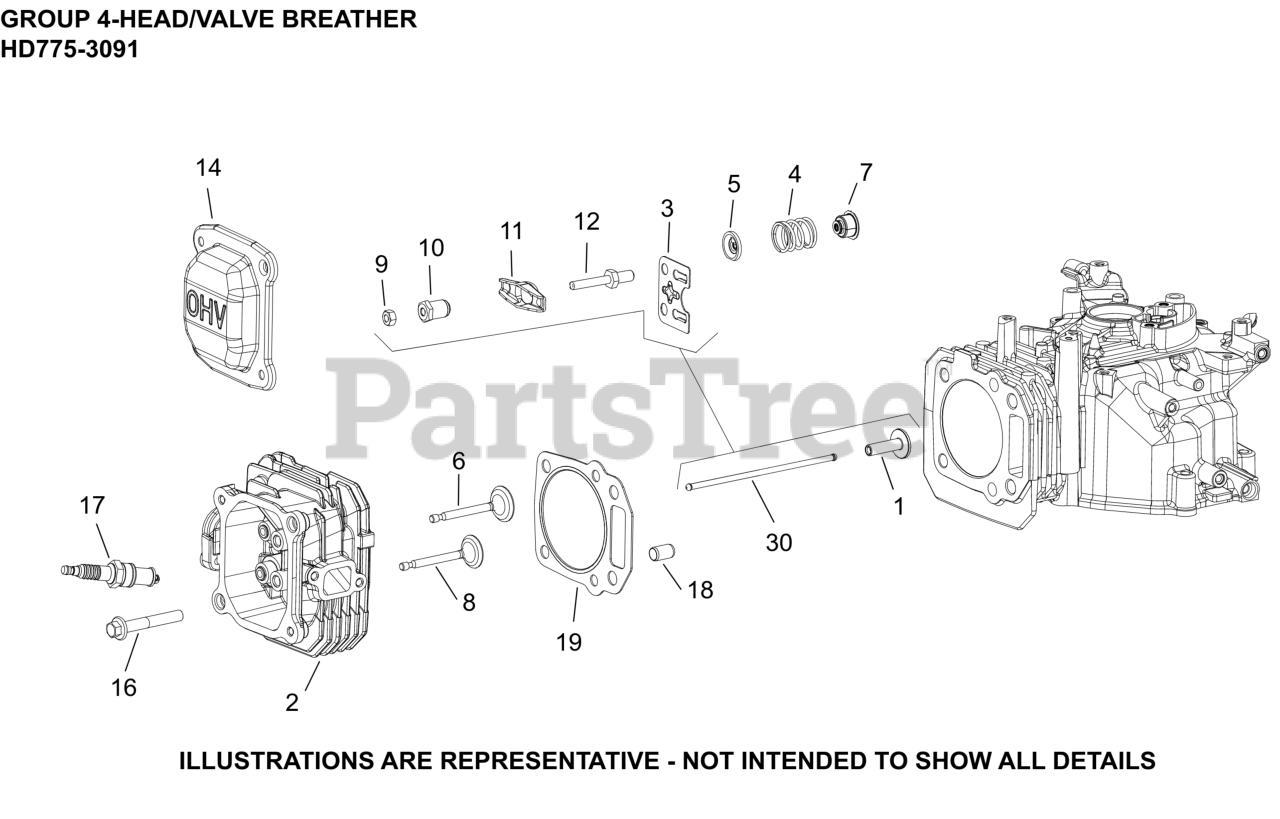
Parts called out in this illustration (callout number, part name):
1	LIFTER, VALVE
2	HEAD, CYLINDER
3	PLATE, PUSHROD GUIDE
4	SPRING, VALVE
5	RETAINER, VALVE SPRING
6	VALVE, INTAKE
7	SEAL, VALVE STEM
8	VALVE, EXHAUST
9	NUT, HEX JAM
10	PIVOT, ROCKER ARM
11	ARM, ROCKER
12	STUD, ROCKER ARM
14	COVER, VALVE
16	SCREW, HEX FLANGE M8
17	PLUG, SPARK 12MM RFI
18	DOWEL, CYLINDER HEAD
19	KIT, HEAD GASKET (CV173)
19	KIT, HEAD GASKET
30	ROD, PUSH
